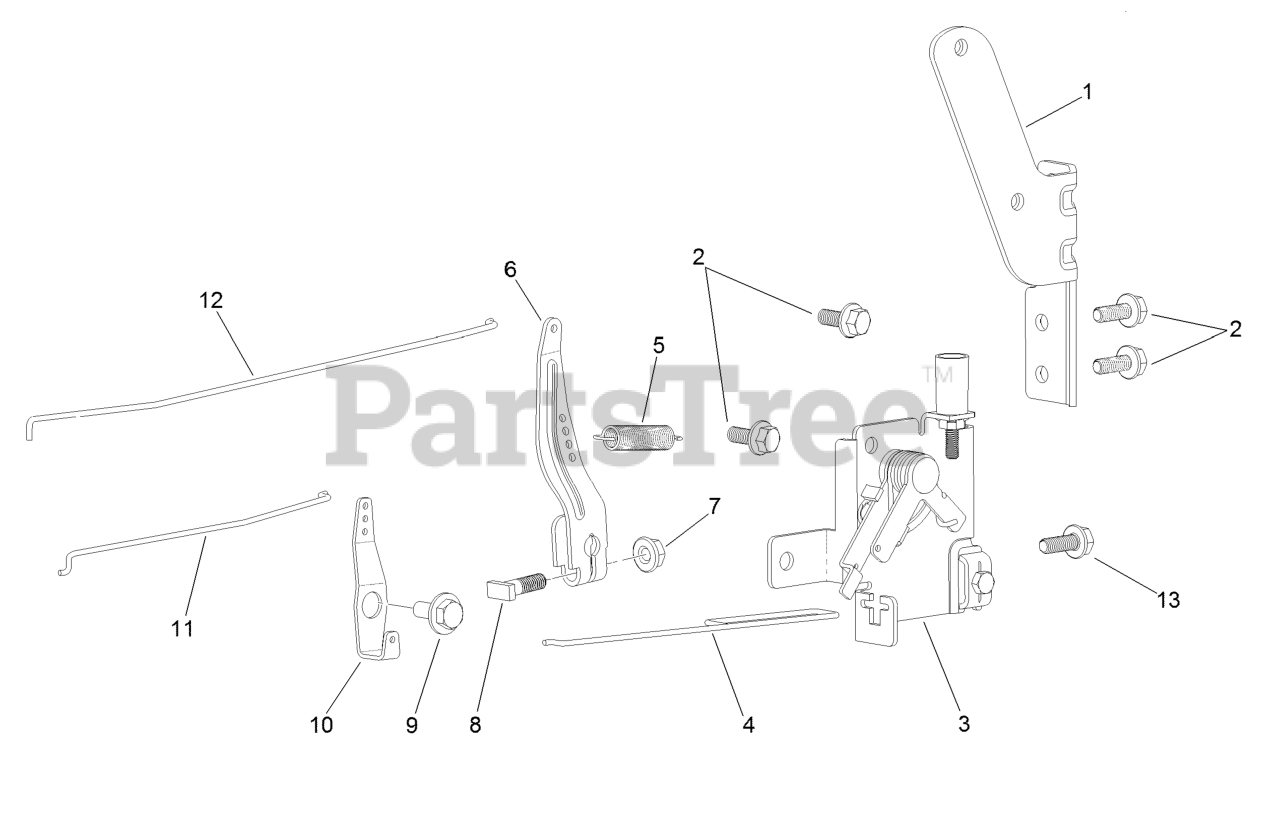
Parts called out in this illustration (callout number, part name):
1	BRACKET-PUMP, FUEL
2	SCREW-HHF
3	CONTROL-THROTTLE
4	ROD-THROTTLE
5	SPRING-GOVERNOR
6	ARM-GOVERNOR
7	NUT-FLANGE
8	BOLT-ARM, GOVERNOR
9	SCREW-SHOULDER, HHF
10	BELLCRANK-CHOKE
11	ROD-CHOKE
12	ROD-GOVERNOR
13	SCREW-HHF
